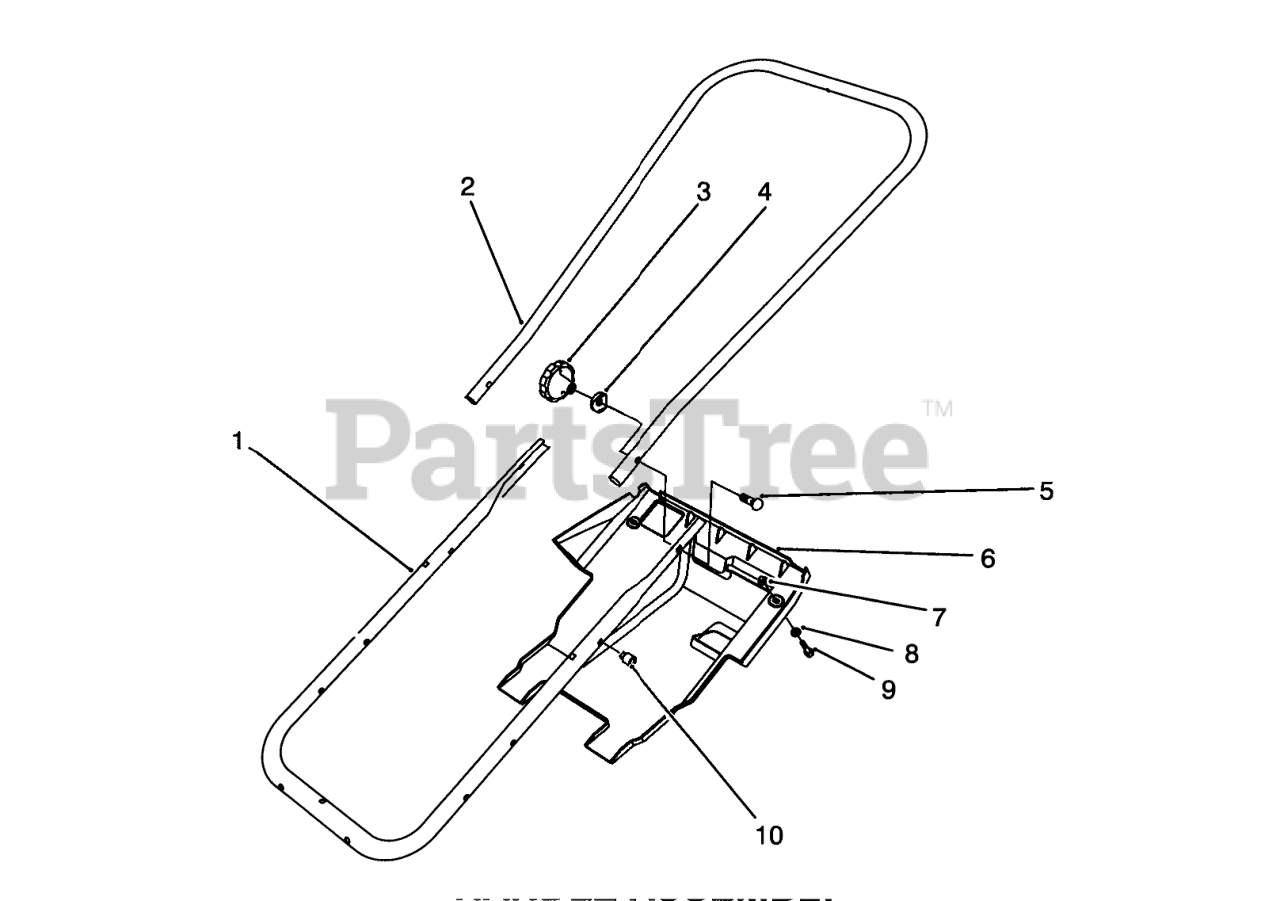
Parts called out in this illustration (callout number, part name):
1	Tube-Frame
2	Handle-Upper
4	WASHER-CURVED
5	SCREW-HANDLE
6	SHROUD
7	Nut-Push
8	WASHER-FLAT
9	SCREW-HWHTF
10	NUT-EXPANSION
